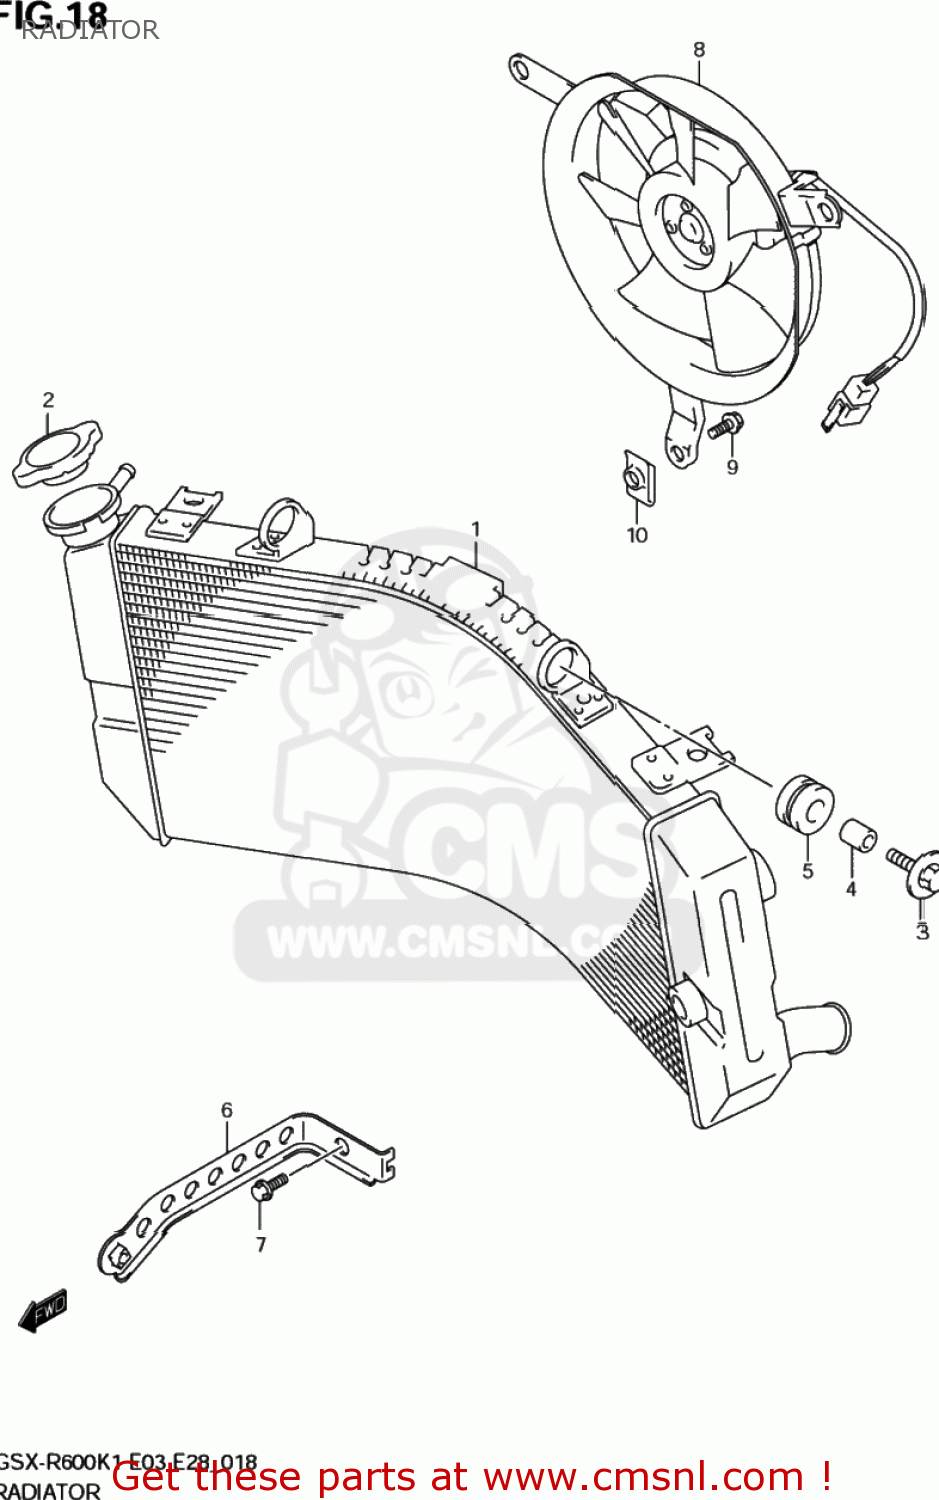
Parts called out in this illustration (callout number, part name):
1	RADIATOR ASSY,
2	CAP COMP,RADIATOR
3	BOLT(6X20)
4	SPACER(6.5X10X12)
5	CUSHION
6	BRACKET,RADIATOR
7	BOLT
8	FAN ASSY,RADIATOR
9	BOLT
10	NUT
